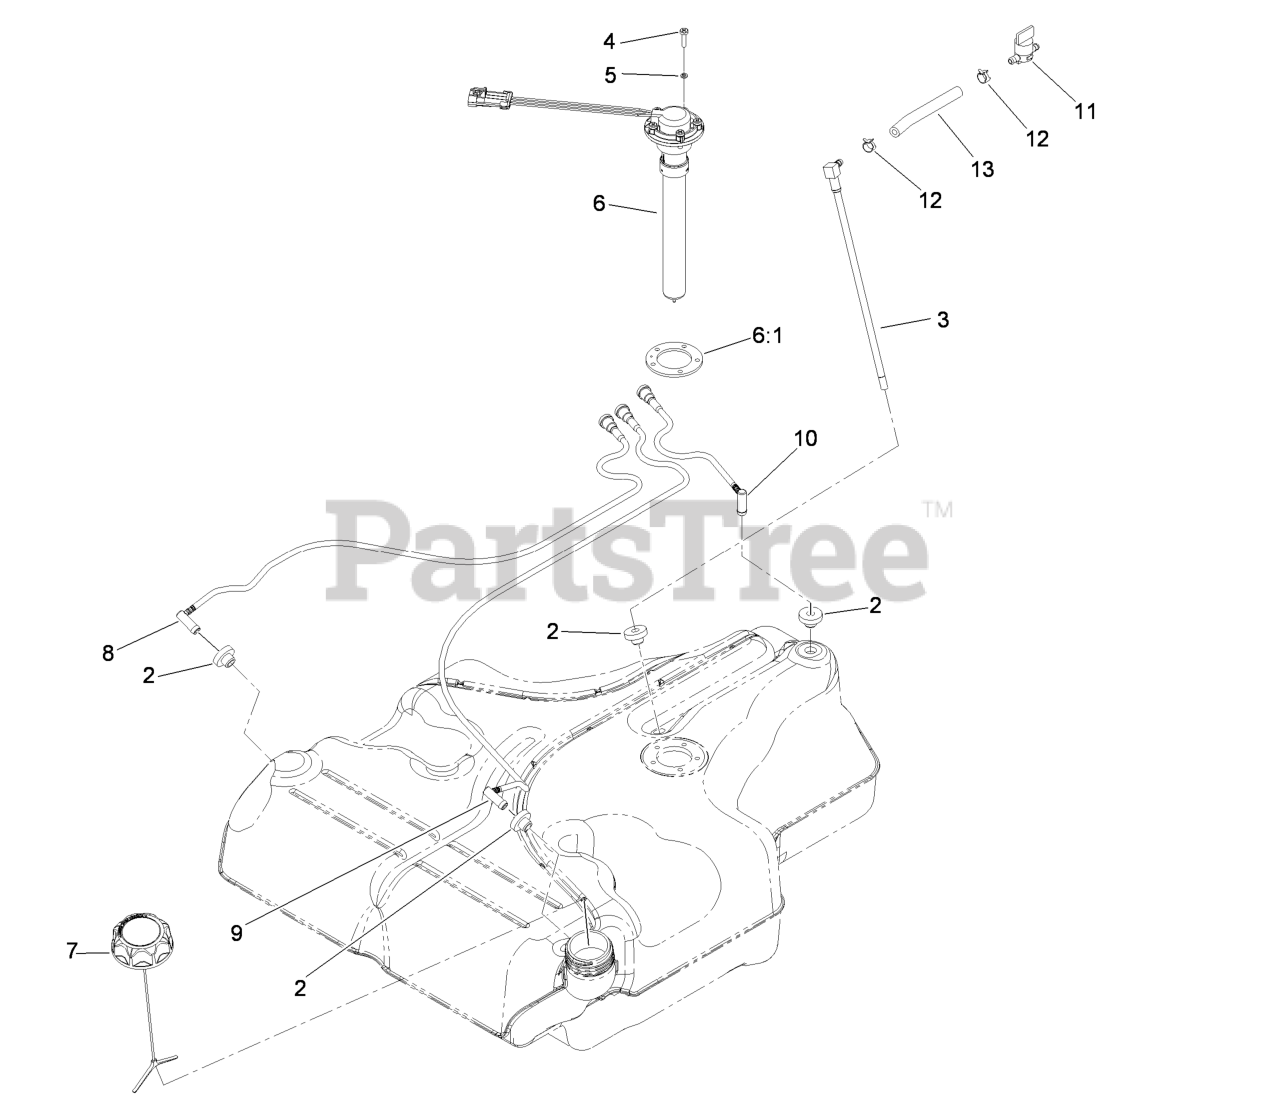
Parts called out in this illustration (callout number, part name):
2	BUSHING
3	FUEL LINE KIT (WITH GROMMET)
4	SCREW-PAN
5	WASHER-LOCK
6:1	GASKET-SENDER, FUEL
8	RH VENT LINE KIT (WITH GROMMET)
9	LH VENT LINE KIT (WITH GROMMET)
10	REAR VENT LINE KIT (WITH GROMMET)
11	VALVE-FUEL
12	CLAMP-HOSE
13	HOSE-FUEL
